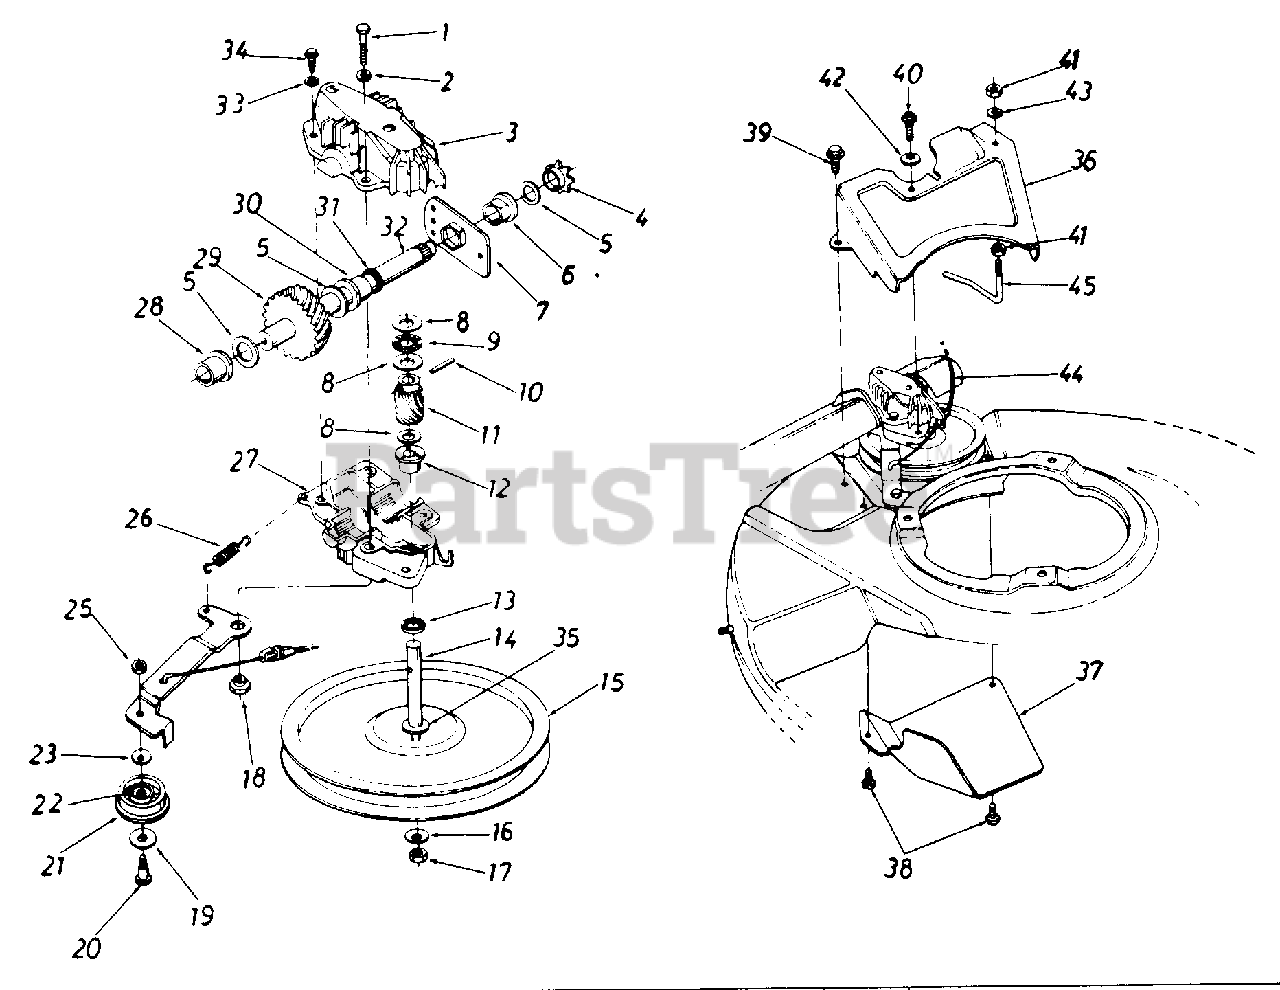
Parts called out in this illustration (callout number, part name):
1	SCREW-HEX 1/4-20 X 1.25
2	LOCK WASHER 1/4 DIA
3	HOUSING HALF-UPPER
4	SPROCKET-7T
5	WASHER-FL
6	BEARING-HEX FLANGE
7	BEARING-CUP HEX
8	WASHER-THRUST.382 X .684
9	BEARING-THRUST
10	PIN-SPRING-SPIR 1/8 X .625
11	GEAR-WORM
12	BEARING-FLANGE
13	SEAL-OIL-.375 ID
14	KIT-TRAN PUL SHFT
15	PULLEY
16	WASHER-SPRING BELL
17	NUT-LH THD-1/4 X 28
18	SPACER-SHLD
19	WASHER-FL .995 X .032
20	SCREW-SHLD
21	KIT-PULLEY
22	BEARING-NEEDLE
23	WASHER-SPRING BELL
25	NUT-HEX 1/4-28
26	SPRING-EXTENSION
27	HOUSING HALF-LOWER
28	BEARING-FLANGE
29	SHAFT-ASSY W/GEAR
30	BEARING-FLANGE
32	SHAFT-ASSY W/GEAR
33	WASHER-LOCK-#10
34	SCREW-HEX WASH HD TAP
35	WASHER-HEX
36	GUARD-BELT
39	SCREW-HEX WASH SF TAPP
40	SCREW-HEX B-TAP 1/4-.62
41	NUT-HEX 1/4-20
42	WASHER-SPRING BELL
43	LOCK WASHER 1/4 DIA
44	CABLE-CLUTCH X 50.0
45	GUARD-BELT
